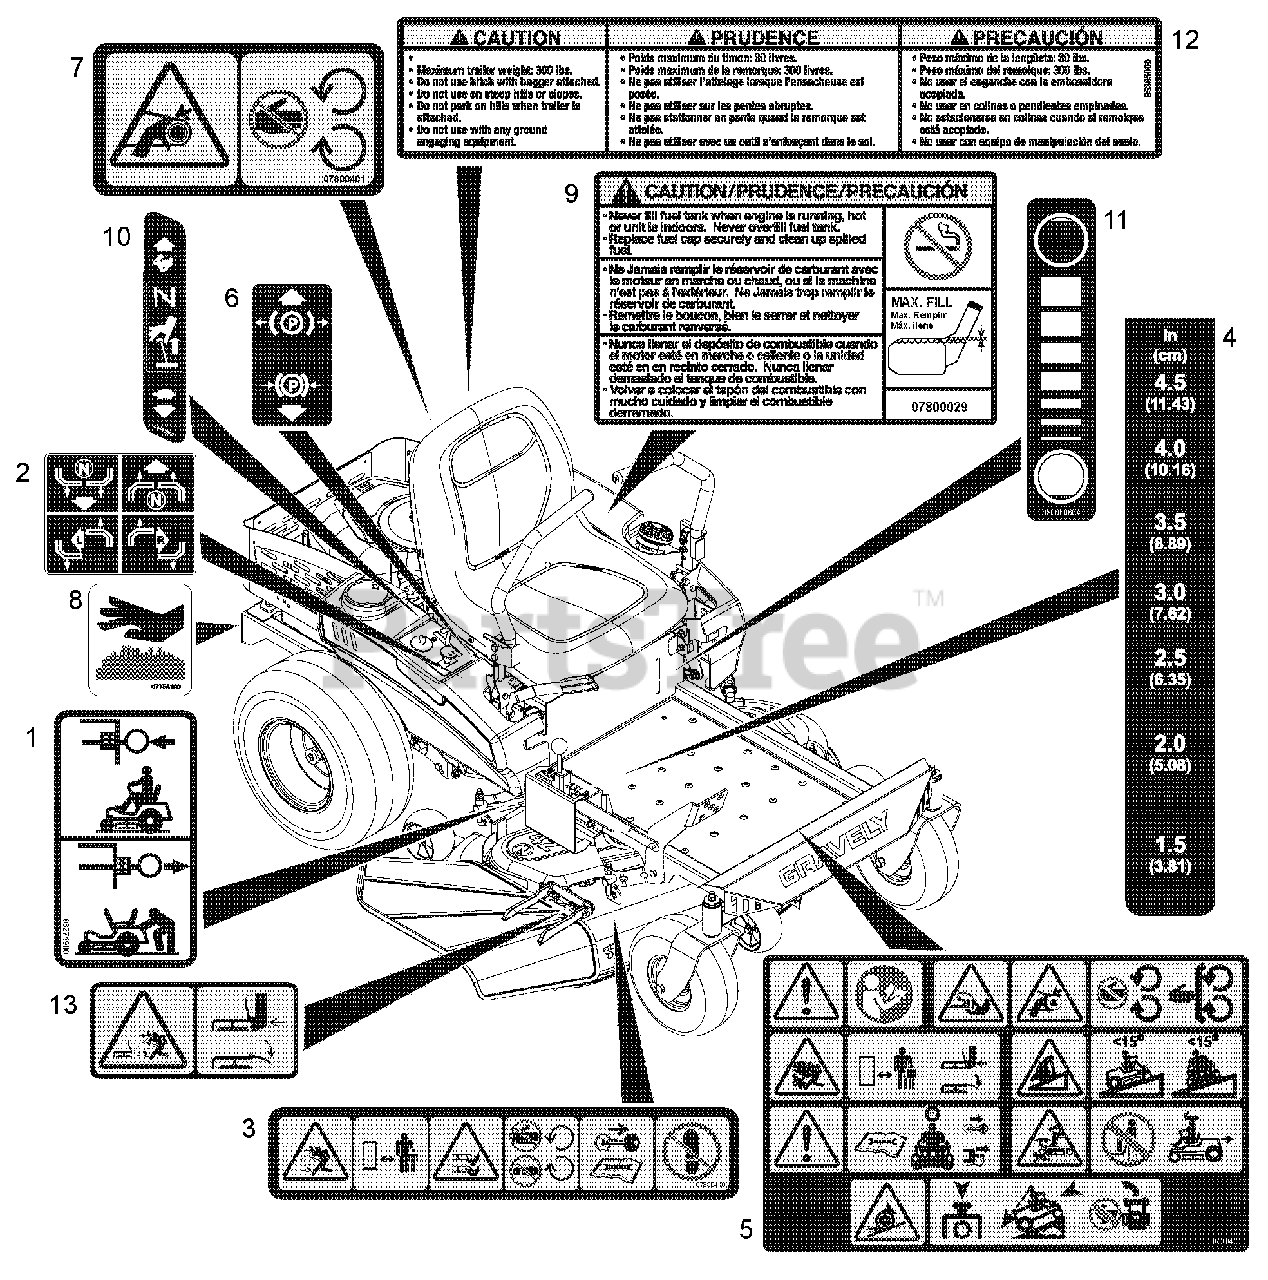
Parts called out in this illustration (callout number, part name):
1	Decal, Transmission Disconnect
2	Decal, Instructional Steering
3	Decal, Safety – Mower Deck
4	Decal, Cut Height
5	Decal, Safety – Main
6	Decal, Parking Brake Lever
7	Decal, Safety – Guarding
8	Decal, Hot Surface
9	Decal, Fuel Warning
10	Decal, Throttle/Choke Combo
11	Decal, Fuel Level
12	Decal, Trailer Hitch (915328)
13	Decal, Safety – Deck Guarding
